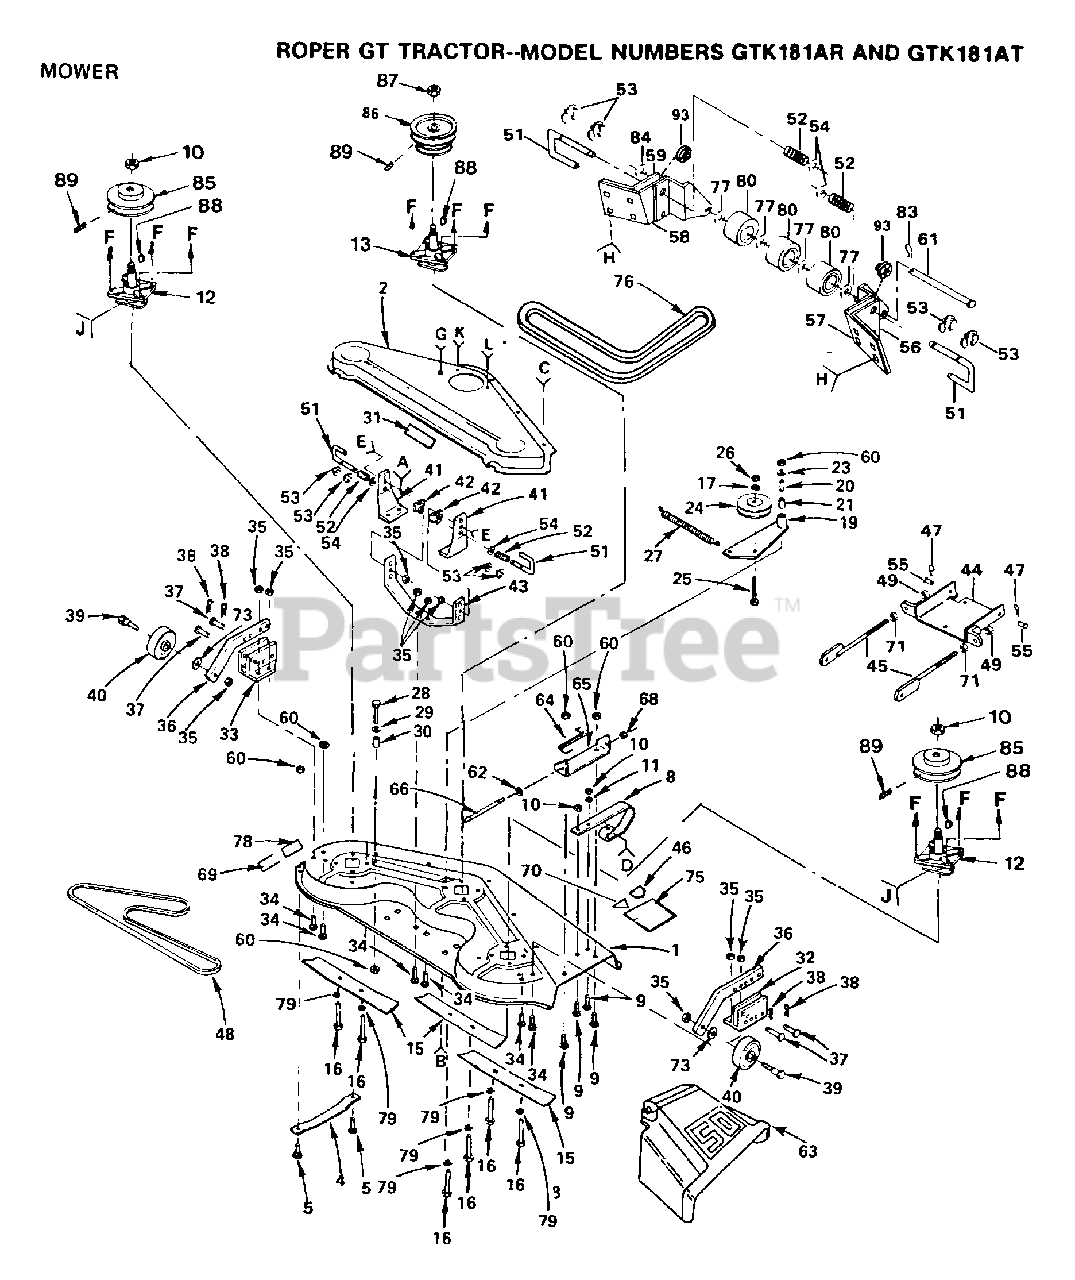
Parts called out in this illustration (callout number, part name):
2	COVER DECK T
4	RUNNER-LH M
5	BOLT
9	BOLT
11	WASHER
16	BOLT.7/16-14X3/4
17	LOCKWASHER
19	ARM ASSY GT
23	WASHER
24	IDLER-FLAT T
26	NUT.HEX.3/8-16UNC
27	SPRING T
28	BOLT
29	WASHER M
30	SPACER SPLIT LT
32	GUAGE WHL BRKT GT
33	GUAGE WHL BRKT GT
34	BOLT
36	GUAGE WHL BAR GT
39	BOLT M
40	WHEEL.GAGE.BLK.PL
41	SUSP BRKT GT
42	SPACER GT
43	SUSP BRACE GT
45	BRACKET.SUSPEN.AS
46	DECAL HYT
47	RETAINER.SPRING
48	V-BELT M
49	NUT LTV
51	RELEASE PIN GT
52	SPRING M
53	KLIP RING
55	CLEVIS PIN GT
56	BRACKET T
57	BRACKET T
58	BRACKET T
59	BRACKET T
61	PIVOT PIN T
62	WASHER
63	DEFLECTOR
66	ROD-HINGE T
68	NUT PUSH M
69	DECAL INSTRUCTION CAUTION
71	NUT
73	WASHER
77	WASHER T
78	DECAL-INST YT
79	LOCKWASHER
80	ROLLER T
83	COTTER PIN
89	SCR - HEX FGD SOCKET 3/8 X 16 X 1/2
93	SPACER T
